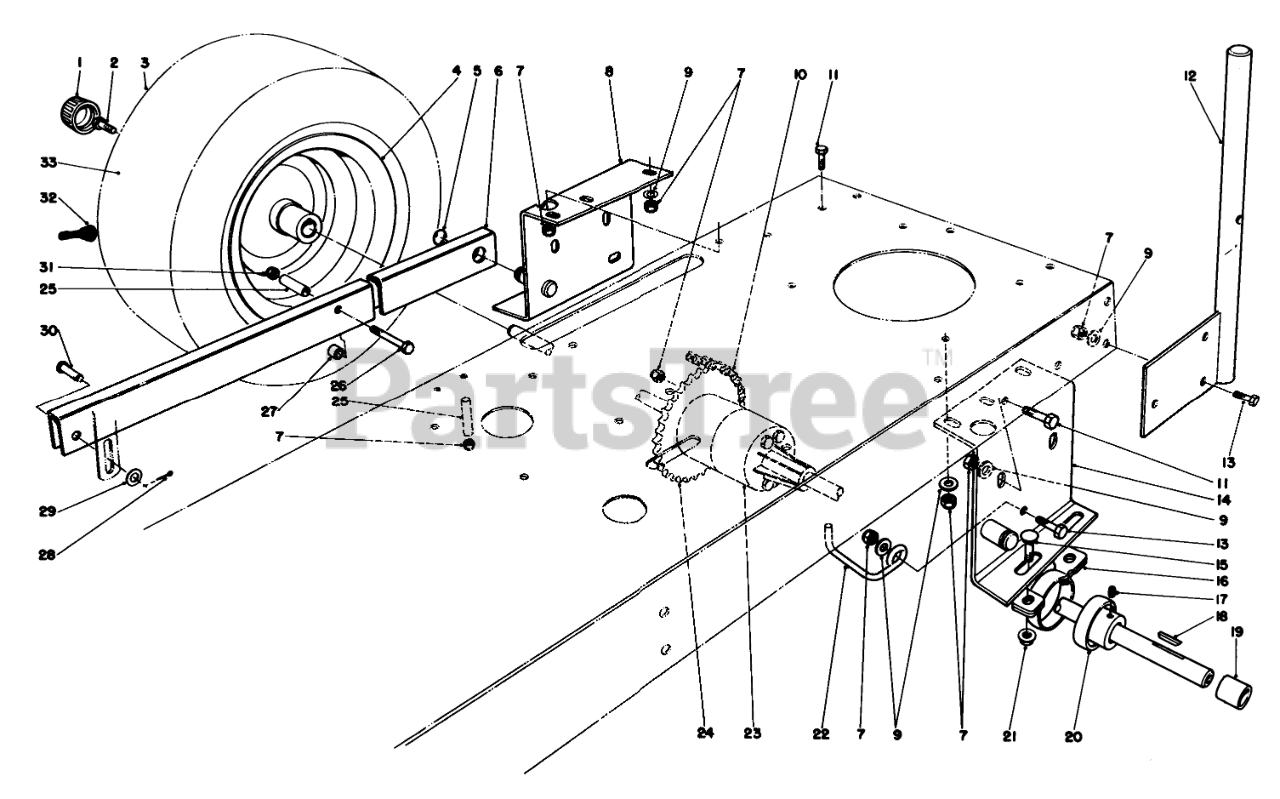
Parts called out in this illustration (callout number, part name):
1	Cap-Hub
2	CAPSCREW 3/8 16 3/4
3	Tire
4	REAR RIM
5	E-RING
6	REAR SUSP ARMR
7	NUT-LOCK, NI
8	Support-Rear Axle R.H.
9	WASHER-PLAIN
10	Chain
11	SCREW-HH
12	Stand Bar
13	SCREW-HH
14	Support-Rear Axle L.H.
15	SCREW-CARR
16	RTNR-PILLOW BLK
17	SCREW-SET, HSH
17	SCREW-SET
19	REAR AXLE SPACER
20	Bearing-Self Aligning (Incl. Ref. #17)
21	NUT-HF
22	BELT GUIDE
23	Differential
24	Sprocket Differential
25	OUTER TUBE SPACER
26	SCREW-HH
27	INNER TUBE SPACER
28	PIN-COTTER
29	WASHER-FLAT
30	PIN-CLEVIS
31	NUT-LOCK, CONE
32	STEM-VALVE
33	TUBE-INNER
